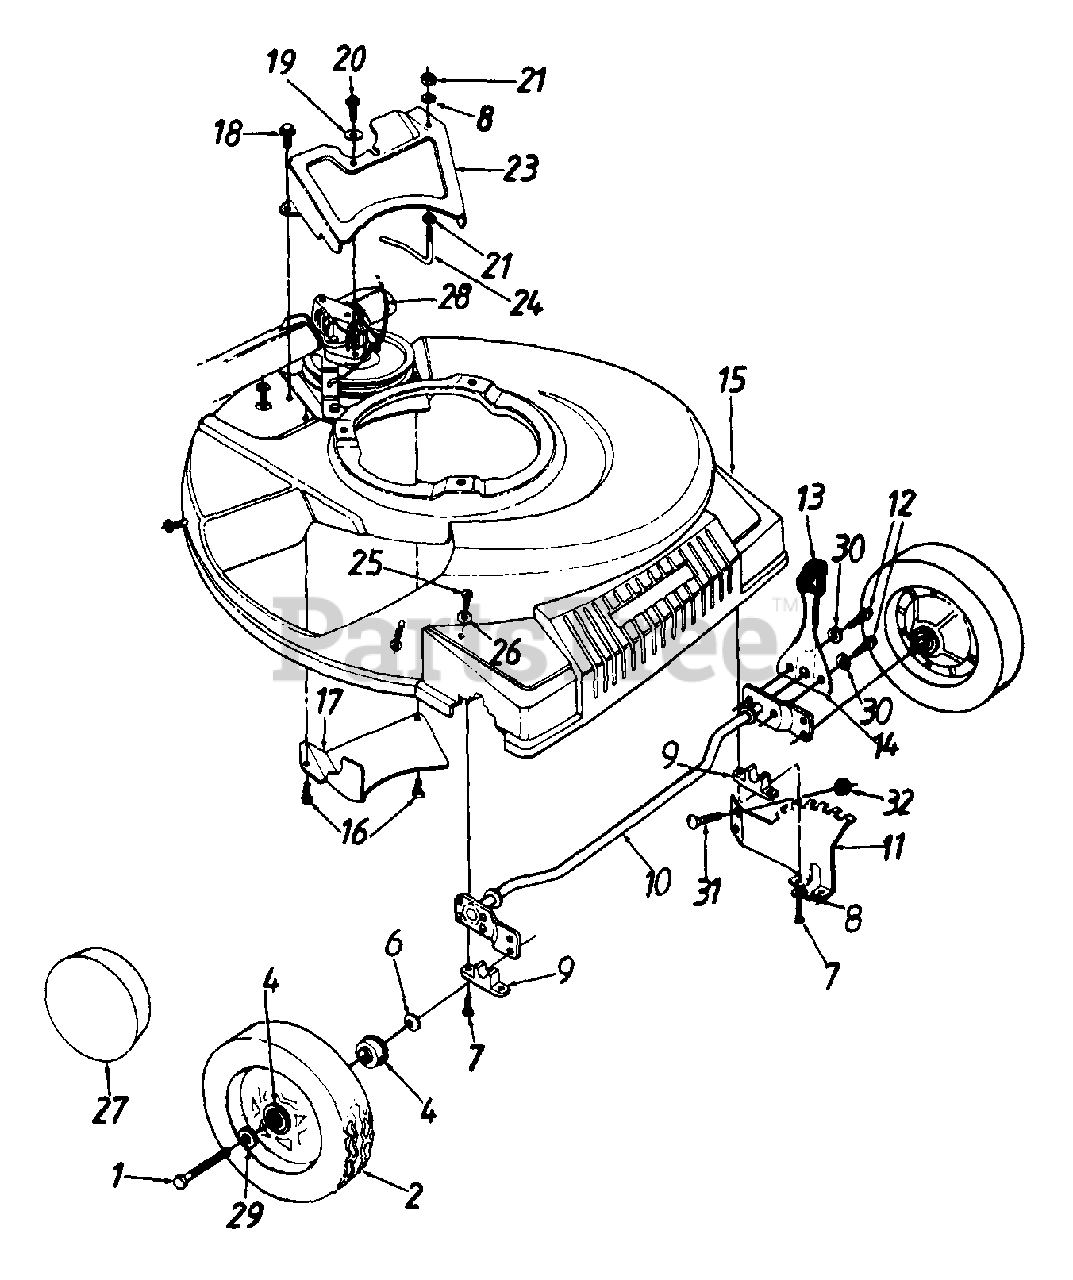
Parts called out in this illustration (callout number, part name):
1	Front Axle Bolt
2	Wheel Ass'y. Comp.
4	Flange Ball Brg..501" I.D.
6	Bell-Wash..380" I.D. x .88
7	Hex Wash. Hd. Scr. 1/4-20 x 1" Lg.
8	L-Wash. 1/4" I.D.
9	Block Bushing
12	Hex Wash. Hd. TT-Tap Scr. 1/4-20 x .38" Lg.
13	Knob
14	Spring Lever
15	Plastic Front End
16	Hex B-Tap Scr. 1/4" x .38"
19	Bell-Wash..265" I.D. x .75"
20	Hex Wash. Hd. B-Tap Scr. 1/4 x .62" (Spec.)
21	Hex Nut 1/4-20 Thd.
25	Torx Truss Hd. Scr. 5/16 x .75"
26	Bell-Wash..345" I.D. x .88" O.D.
27	Hub Cap
28	S.P. Cable 50" Lg.
29	Wave Wash..51" I.D. x .75" O.D.
30	External L-Wash. 1/4" I.D.
31	Carr. Bolt 1/4-20 x .5" Lg.
32	Hex L-Nut 1/4-20 Thd.
